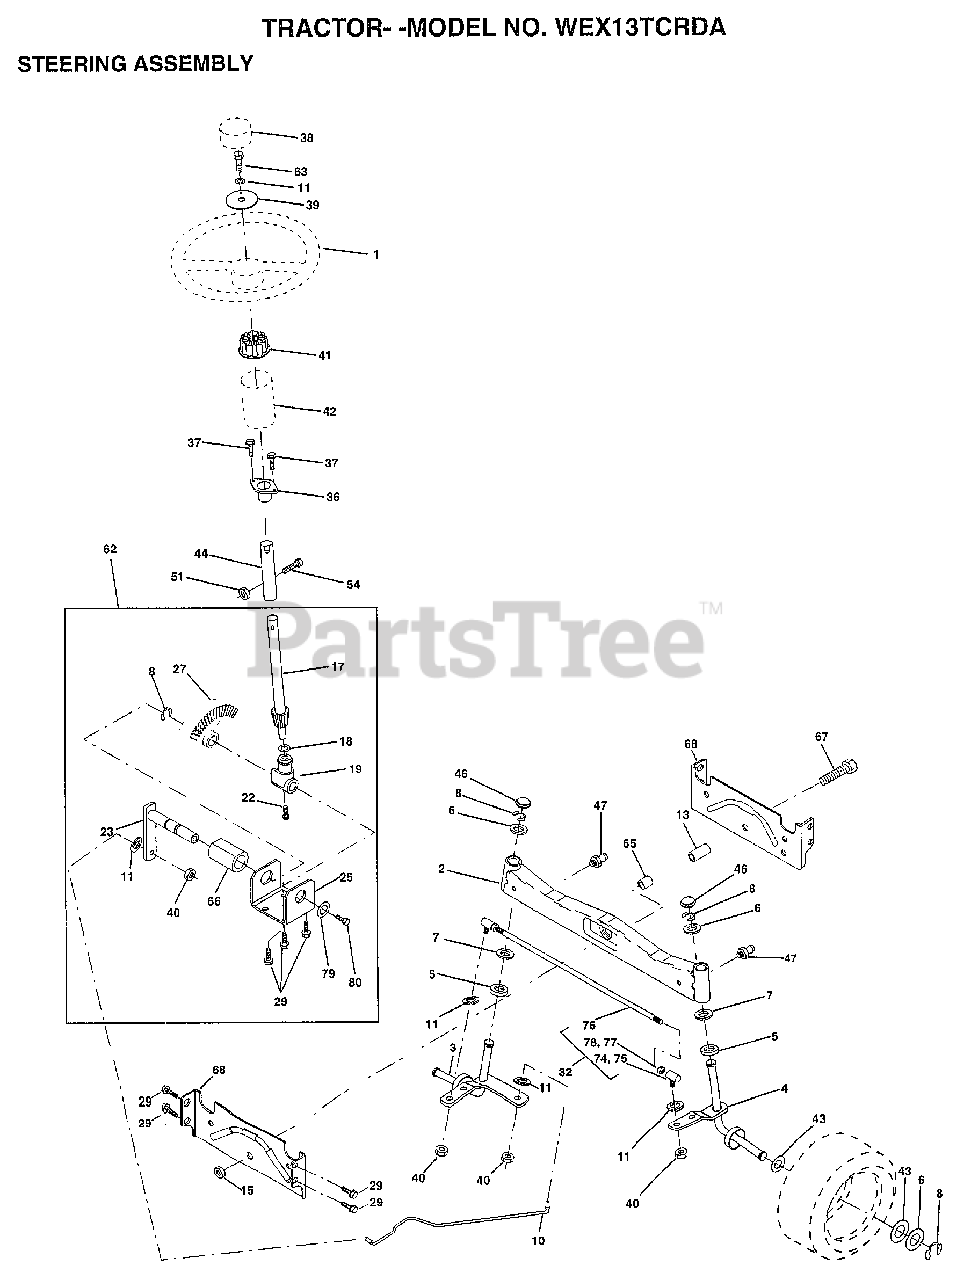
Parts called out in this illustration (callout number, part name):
1	WHEEL STR AYP BLK
3	"SPINDLE ASM,LH"
4	"SPINDLE ASM,RH"
5	WASHER .T
6	WASHER
7	WASHER
8	RING
10	LINK.DRAG
11	LOCKWASHER
13	BEARING.FRT.SPACER.AXLE
15	"NUT-LOC,FLANGE LT"
17	SHAFT ASM STEERIN
18	THRUST WASHER
19	SUPPORT.SHAFT.STEER
22	SCREW.HX.WSH.HD
23	SHAFT.ASM.PITMAN
25	BRKT-STEERING
27	GEAR SECTOR
29	SCREW
32	ROD.ASM.TIE.BALL
36	BUSHING.STEERING
37	"SCREW-TT,10-32 FL"
38	CAP STEER AYP
39	WASHER T
40	GRIPCO NUT
41	ADAPTER LT
42	BOOT.STEER.PL
43	WASHER
44	EXT SHAFT STEERIN
46	CAP
47	ZERK M
51	NUT
54	BOLT
62	KIT.STEER.ASM
63	BOLT
65	SPACER AXLE
66	"BEARING-ARM,PITMA"
67	BOLT
68	BRACE AXLE
74	JOINT.RH
75	JOINT.LH
77	NUT
78	NUT
79	WASHER
80	BOLT.HX.NYLON3/8-16X3/
